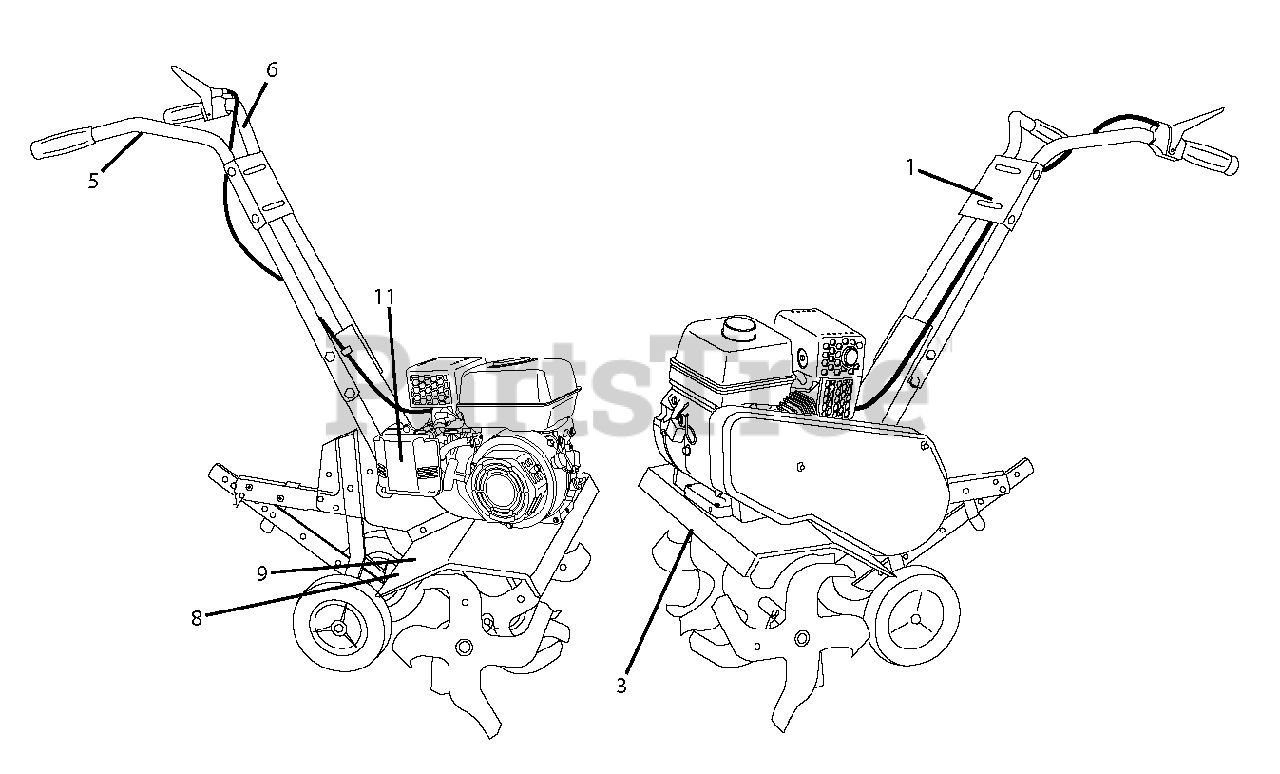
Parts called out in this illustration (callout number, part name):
1	DECAL.CONSOLE.TILLER.YELLOW.PP
3	DECAL.TINE.SHIELD.HD.YELLOW.PP
5	DECAL TI
6	DECAL.TINE.CONTROL.ENG/FR
9	DECAL WARNING
11	DECAL,ETHANOL E85 WARNING
